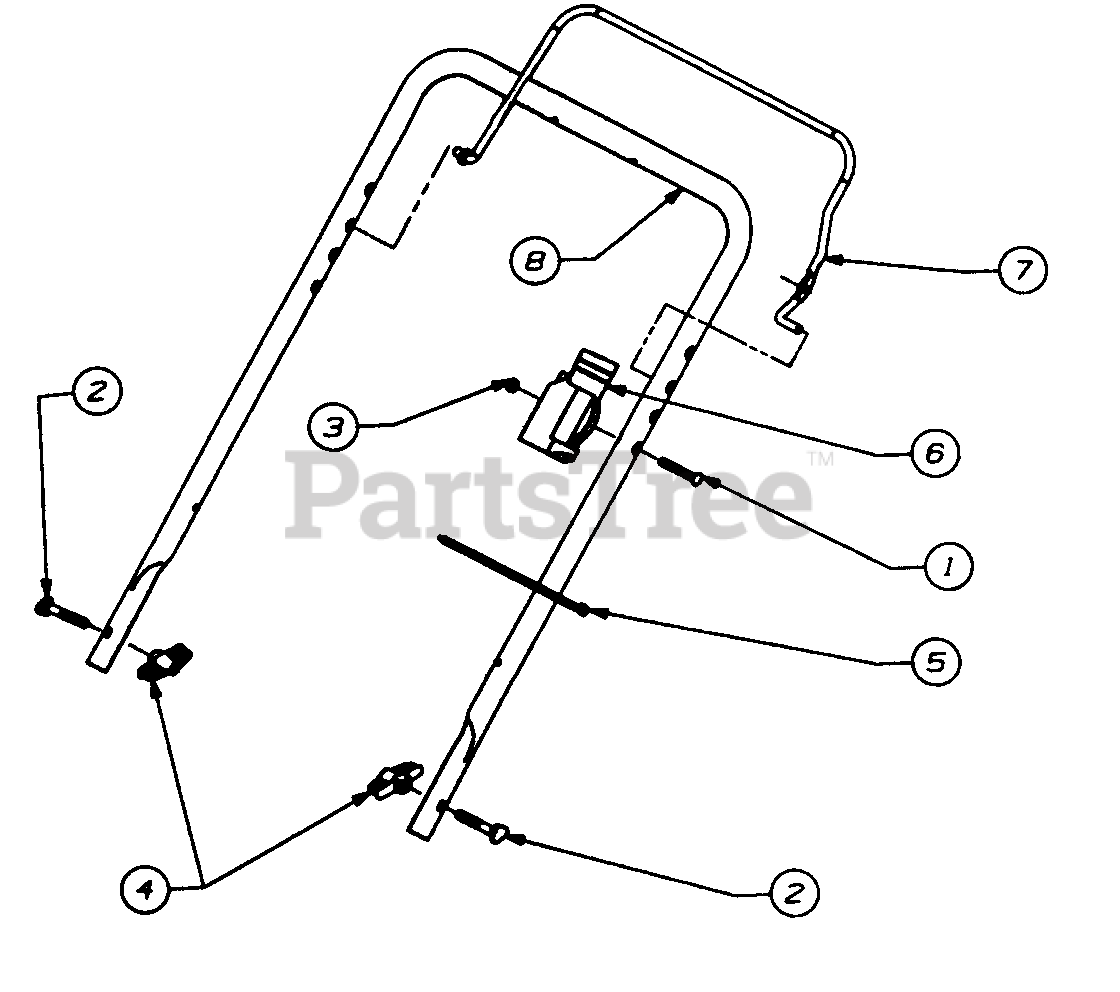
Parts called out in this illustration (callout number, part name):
1	Screw - Oval C-Sink L
2	Bolt - Carriage
3	Nut Insl. Lock
4	Knob - Handle
5	Tie Cable
6	Body - Lever Control
7	Handle Ass'y. Control
